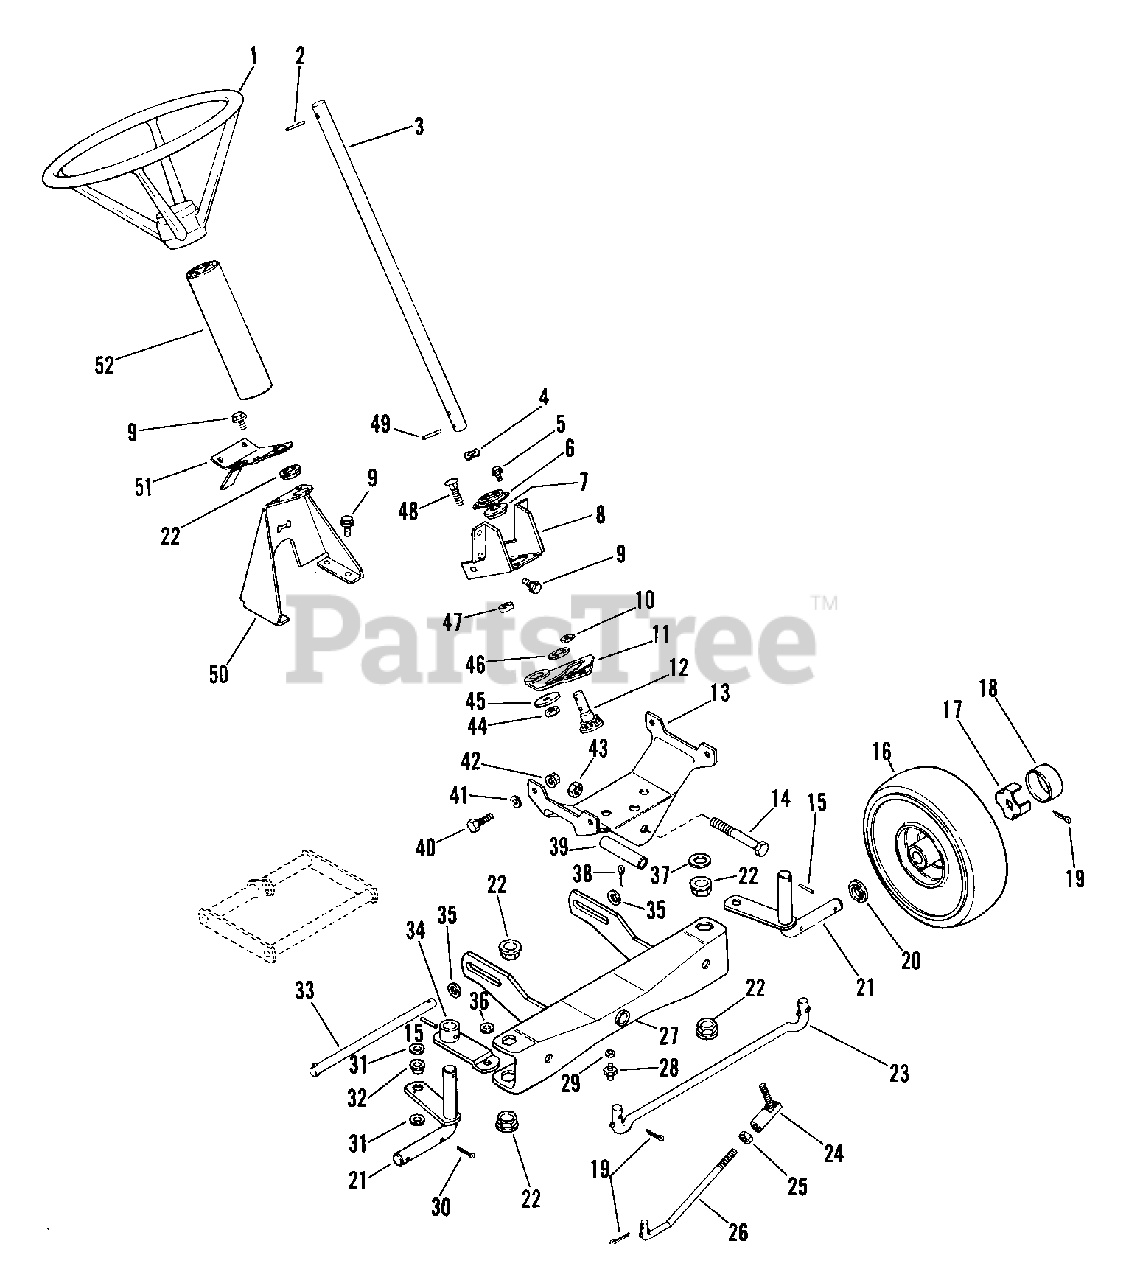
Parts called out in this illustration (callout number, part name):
1	STEERING WHEEL
2	PIN-ROLL .250X1.75
3	STEERING SHAFT
4	WSHR-HDND-STL-THR.515X.97X.062
5	SCR-TAP 10-24X.25 CRSLPH PL 1A
6	RETAINING PLATE
7	BSHG-FLG .625X1.156X.375 SI
8	STEERING BRACKET
9	SCR-TAP .312-18X.50 HWH PL TR
10	NUT-LK .375-24 PL
11	STEERING GEAR
12	PINION
13	AXLE BRACKET
14	BLT-HEX .50-13X4.00 PL GR2
15	PIN-GRV .250X1.25 TP A
16	WHL
16	T/WHL ASSY FRT
16	TIRE 4.10/3.50-4
16	T/WHL ASSY
16	TIRE
16	ZERK FITTING
16	BSHG-FLG .750X1.380X.750X1.557
16	BRG-BALL .752X1.50X.50
16	WHL-COMP
17	SPINDLE CUP
18	HUB CAP
19	PIN-COTR .12X1.0 PL
20	SPINDLE WASHER
21	R.H. WHEEL SPINDLE
21	L.H. WHEEL SPINDLE
22	FLANGE BUSHING
23	TIE ROD
24	BALL JOINT
25	NUT .375-24 PL
26	DRAG LINK
27	AXLE
28	SPIN DRIVE ZERK FITTING
29	WSHR-FL-STL .265X.500X.087 PL
30	PIN-COTR .12 X 1.25 PL
31	WSHR-FL-STL .505X.875X.024 PL
32	BSHG-FLG.500X.625X.312X.750NY
33	HANGER PIN
35	WSHR-FL-STL .505X.880X.072 PL
36	WSHR-FL-STL.406X.812X.065PL
37	WSHR-FL-STL .755X1.375X.062 PL
38	PIN-COTR .09X.75 PL
39	TUBE AXLE PIVOT
40	BLT-SERRDHD SL .31-18X.75 YZ
41	WSHR-LK .375X.094 MED PL
42	NUT-FLG. .312-18 PL
43	NUT-LK-CTR .50-13
44	NUT-LK-JAM-CTR .375-16 PL
45	WSHR-FL-STL .390X1.500X.125
46	WSHR-FL-STL .630X1.250X.062 PL
47	SPACER .380X.750X.236
48	BLT-RDHDSQSHNK .38-16X1.00 PL
49	PIN-ROLL .188X1.00
50	STEERING SUPPORT
